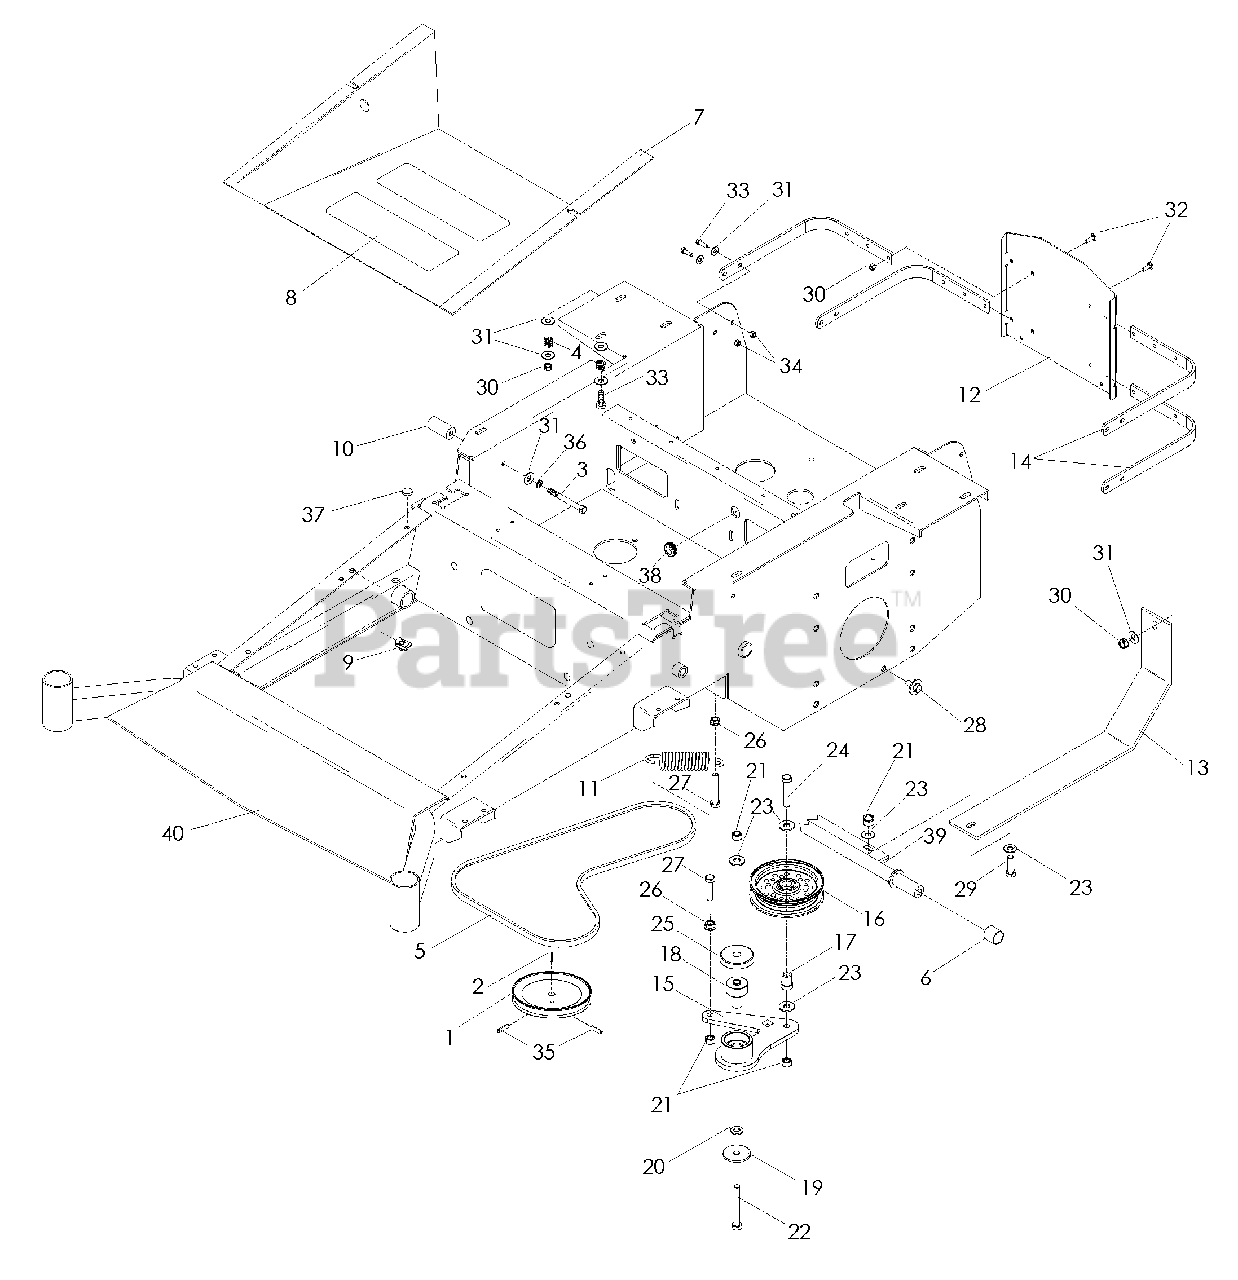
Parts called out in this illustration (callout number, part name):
3	Hcs 5/16-18 X 4
4	Spring, Fuel Tank
5	Belt, Pump
6	Spacer, Strut
7	Foot Plate
8	Pad, Anti-Skid
9	Retainer, 5/16-18 U-Type
10	Spacer-Tank
12	Guard, Black
13	Skid Plate
14	Strap, Black
15	Arm, Idler W/Bearings
16	Pulley, Idler Hd
17	Bushing, Idler Flange
18	Pivot Bearing
19	Washer 3/8 Special
20	Washer 3/8 Sae Flt
21	Nut 3/8-16 Hex Nyloc
22	Hcs 3/8-16 X 3
23	Washer 3/8 Std Flt
24	Hcs 3/8-16 X 2
25	Shield, Dust
26	Nut 3/8-16 Hex Whizlk
27	Hcs 3/8-16 X 1 1/2
28	Blade Bolt/Washer
29	Hcs 3/8-16 X 1
30	Nut 5/16-18 Hex Ctrlk
31	Washer 5/16 Std Flt
32	Rhsnb 5/16-18 X 3/4
33	Hcs 5/16-18 X 1
34	Nut 5/16-18 Hex Nyloc
36	Washer 5/16 Lock
38	Grommet Fuel Line
39	Cross Shaft Strut
